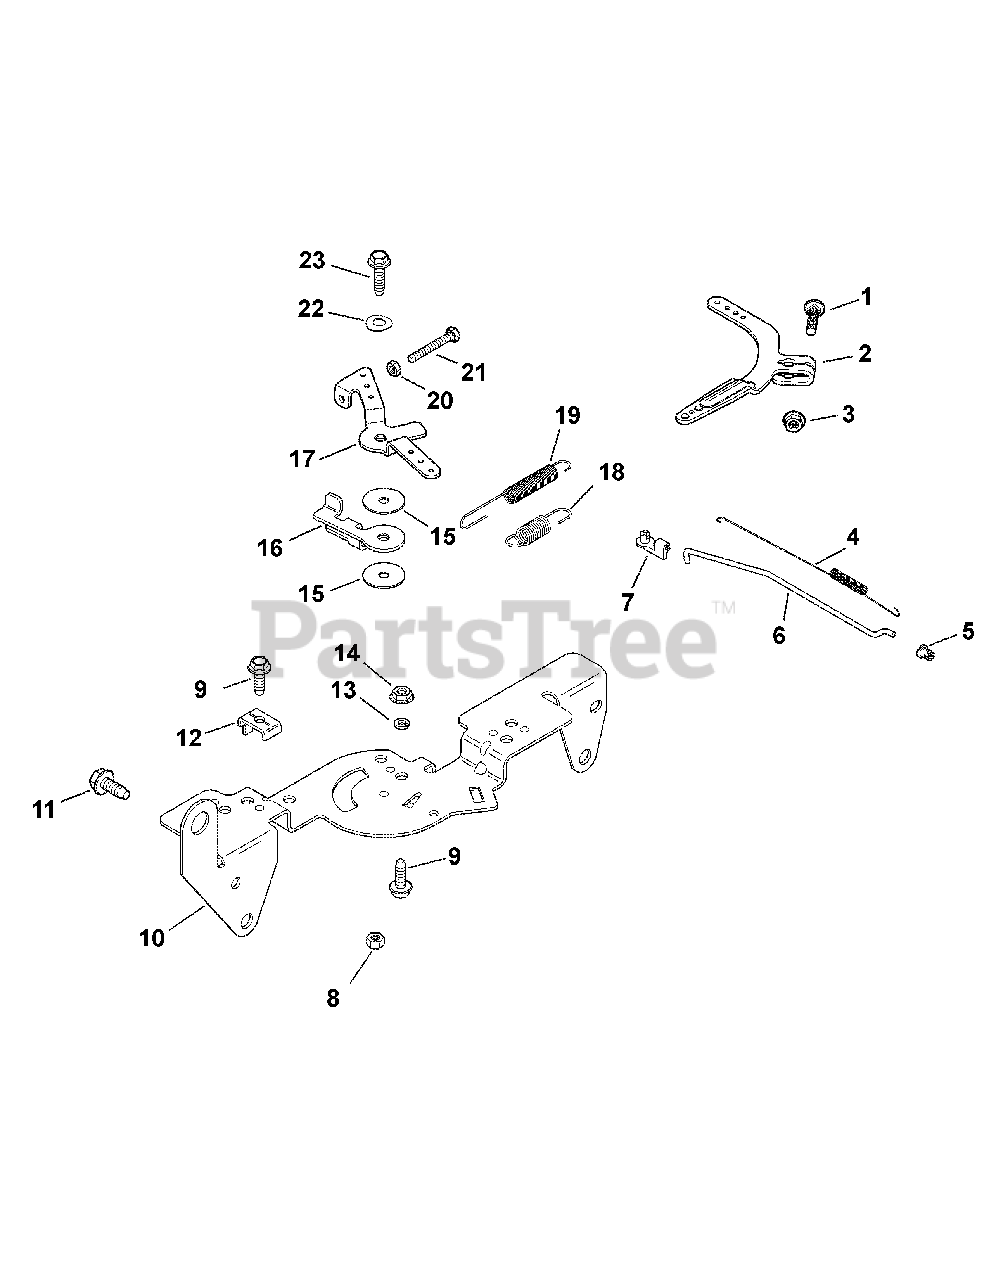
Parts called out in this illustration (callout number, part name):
1	Bolt, Rd Hd Sq Neck, M6x1.0x25
2	Lever, Governor
3	Nut, Flg, M6 x 1.0
4	Spring, Linkage
5	Bushing, Linkage Retaining
6	Linkage, Throttle
7	Bushing, Throttle Linkage
8	Nut, Lock M5 x .8
9	Screw, Flg Thd Frm M5x0.8x16
10	Bracket, Control
11	Screw, Flg Thd Frm M6x1.0x16
12	Clamp, Cable
13	Washer, Spring Lock, 1/4"
14	Nut, Flg, M5 x .8
15	Washer, Flat, 5.5 mm
16	Lever, Throttle Actuator
17	Lever, Throttle Control
18	Spring, Governor
19	Spring, Throttle Limiter
20	Nut, M4 x 0.7
21	Screw, Cap, M4 x .7 x 30
22	Washer, Spring, 1/4"
23	Screw, Flg Thd Frm, M5 x .8 x 20
